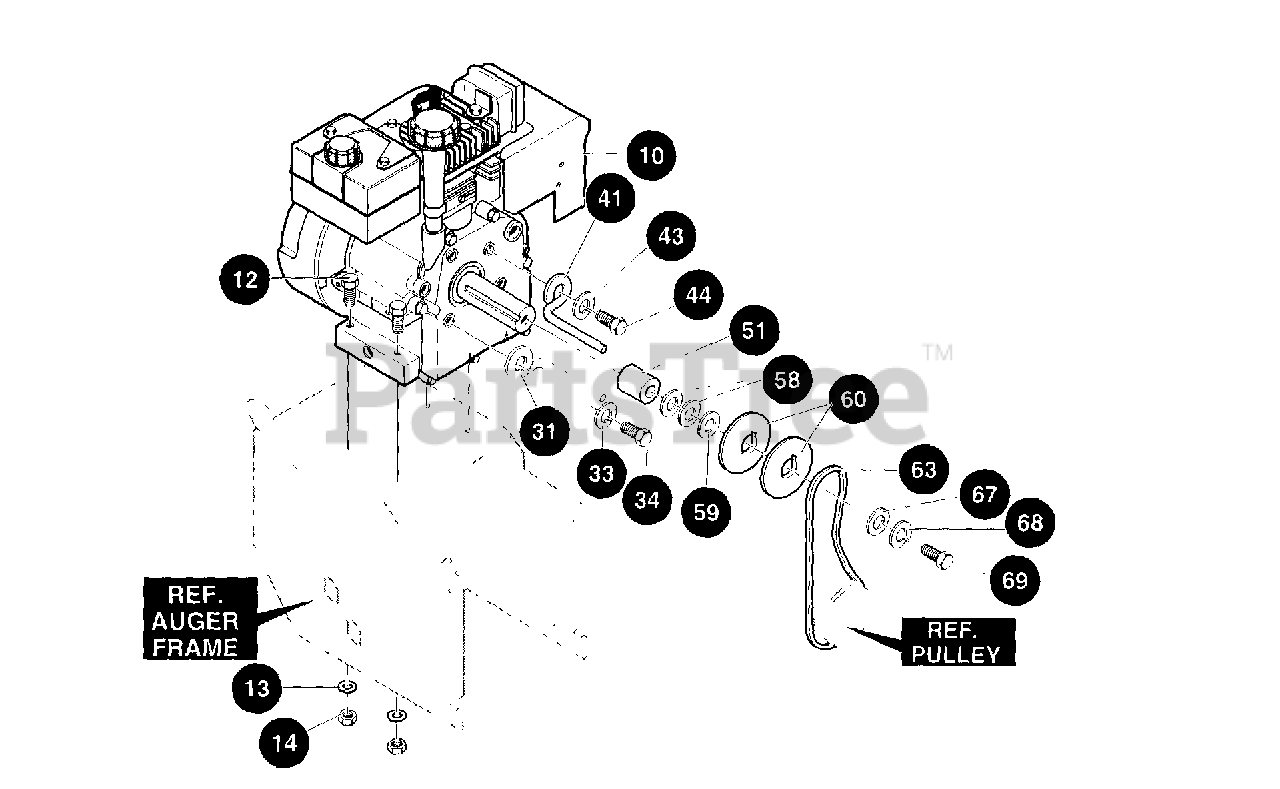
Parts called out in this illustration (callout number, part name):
10	See Engine Manual
12	Screw, 5/16-18 x 1.25
13	Flatwasher, .344 x .69 x .065
14	Nut, 5/16-18
31	Guide, Rod Belt, RH
33	Washer, .328 x .60 x .09
34	Screw, 5/16-24 x .625
41	Guide, Rod Belt RH
43	Washer, .328 x .60 x .09
44	Screw, 5/16-24 x .625
51	Spacer, Slev .75 x 1.25 x 1.32
58	Flatwasher 765 x 1.12 x .06
59	Spacer, Slev .753 x 1.12 x .38
60	Pulley, Eng V4L 3.00 x .75
63	Belt, V4L 35.23 Lg
67	Flatwasher
68	Washer, Regsptlk
69	Screw, 3/8-24 x 1.00
